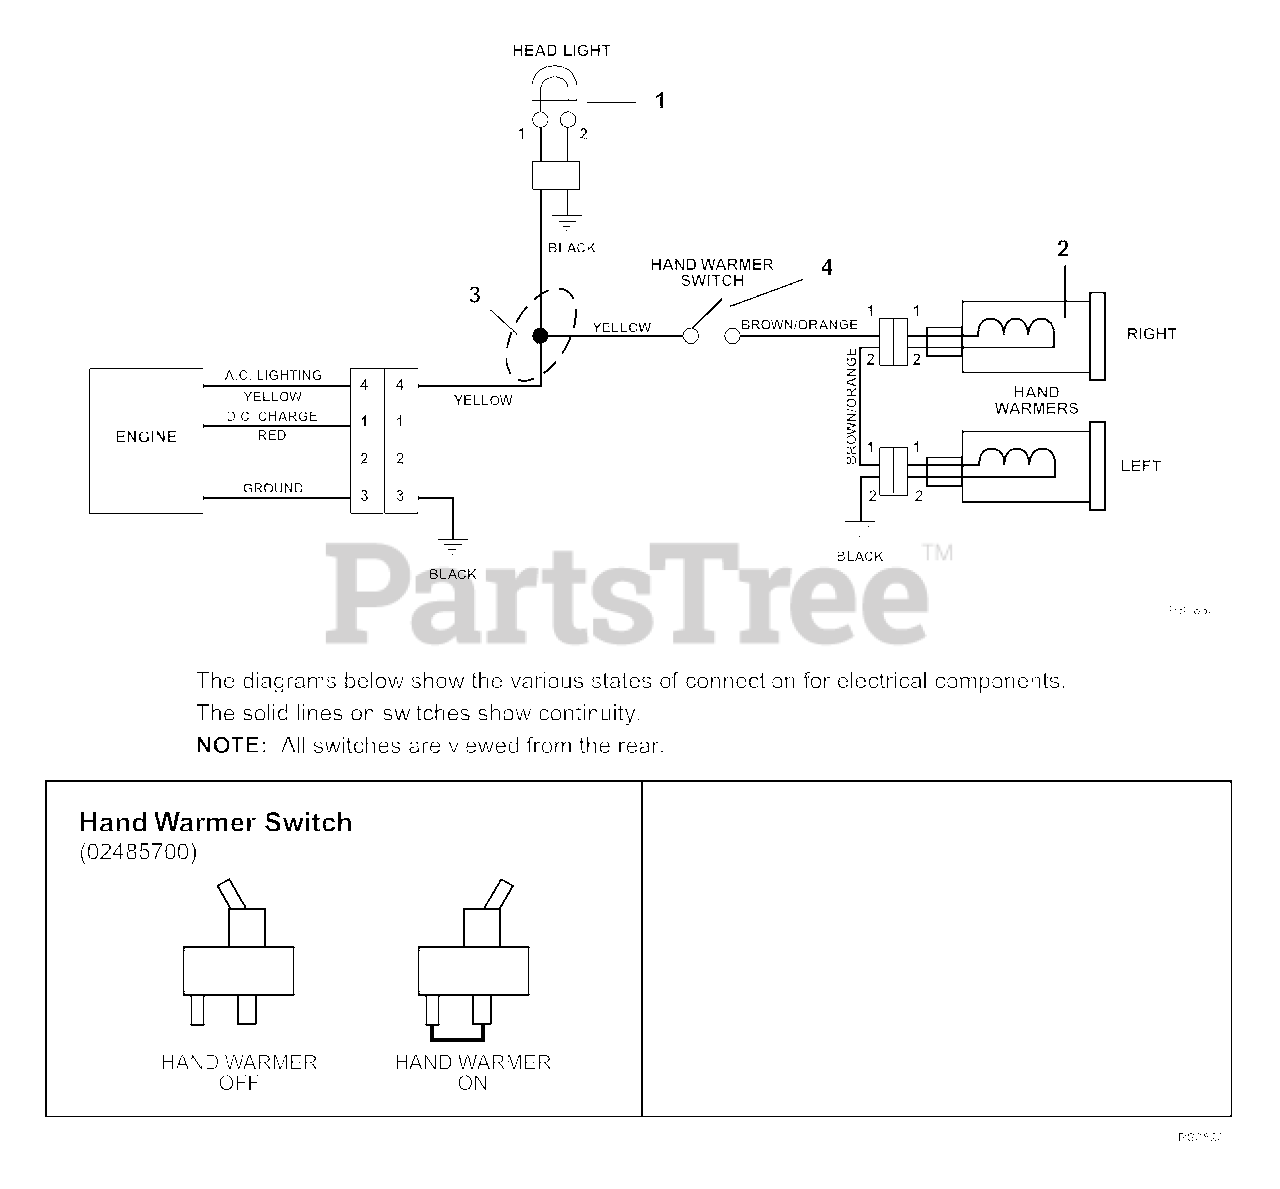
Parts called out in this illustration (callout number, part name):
1	HEADLAMP, OVAL W/ 1156 BULB
2	WARMER, HAND W/TERMINAL
3	HARNESS, WIRE-LIGHT,HANDWARMER
4	SWITCH, ON/OFF
02485700	SWITCH, ON/OFF
